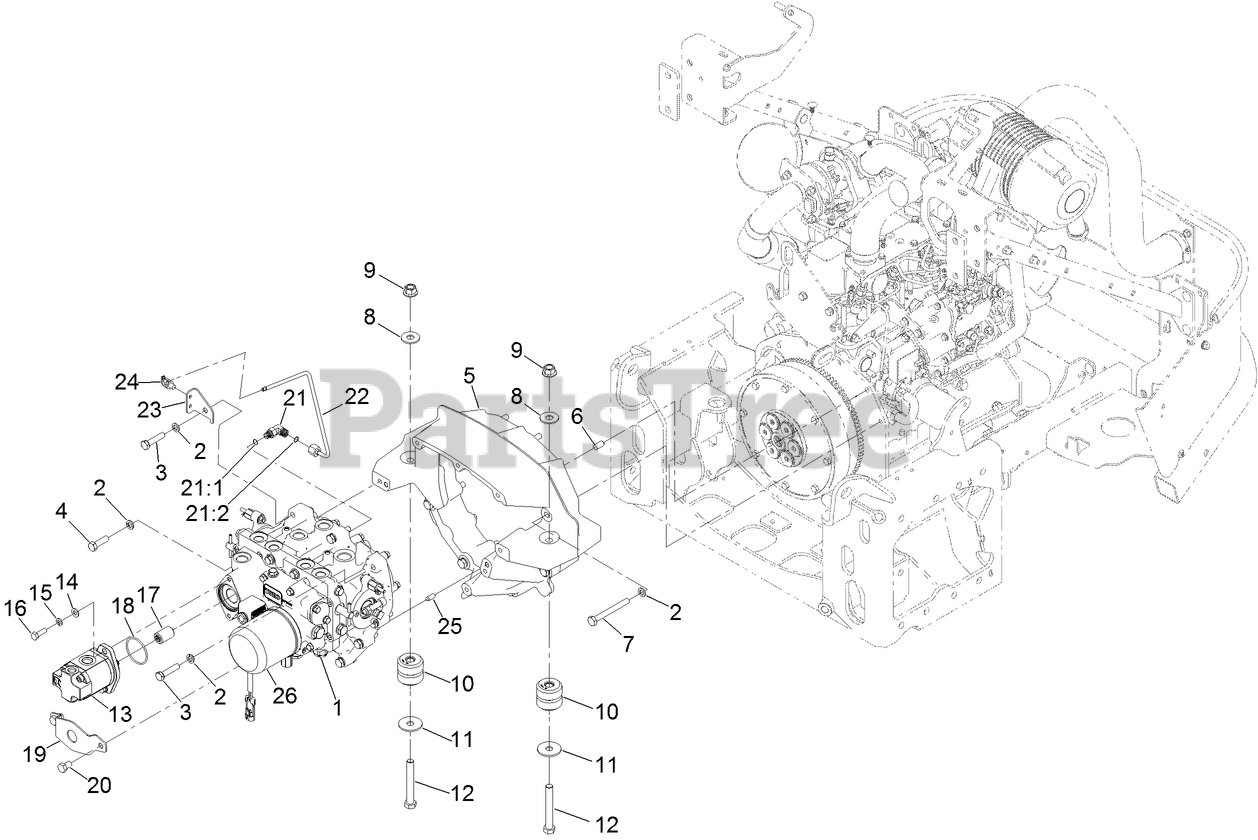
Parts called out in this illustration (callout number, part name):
1	TRANSMISSON ASM
2	WASHER-LOCK
3	SCREW-HH
4	SCREW-HH
5	HOUSING-FLYWHEEL
6	PIN-DOWEL
7	SCREW-HH
8	WASHER-FLAT
9	NUT-LOCK
10	MOUNT-ISOLATOR
11	WASHER-THRUST
12	SCREW-HH
13	HYD GEAR PUMP ASM
14	WASHER-PLAIN
15	WASHER-LOCK
16	SCREW-HH
17	COUPLER-SPLINE
18	O-RING
19	SHIELD-SEAL
20	SCREW-HH
21	FITTING-ELBOW, 90 DEG
21:1	O-RING
21:2	O-RING
22	TUBE ASM
23	SUPPORT-TUBE
24	CLIP-TIE
25	PIN-DOWEL
26	FILTER-OIL, HYD
